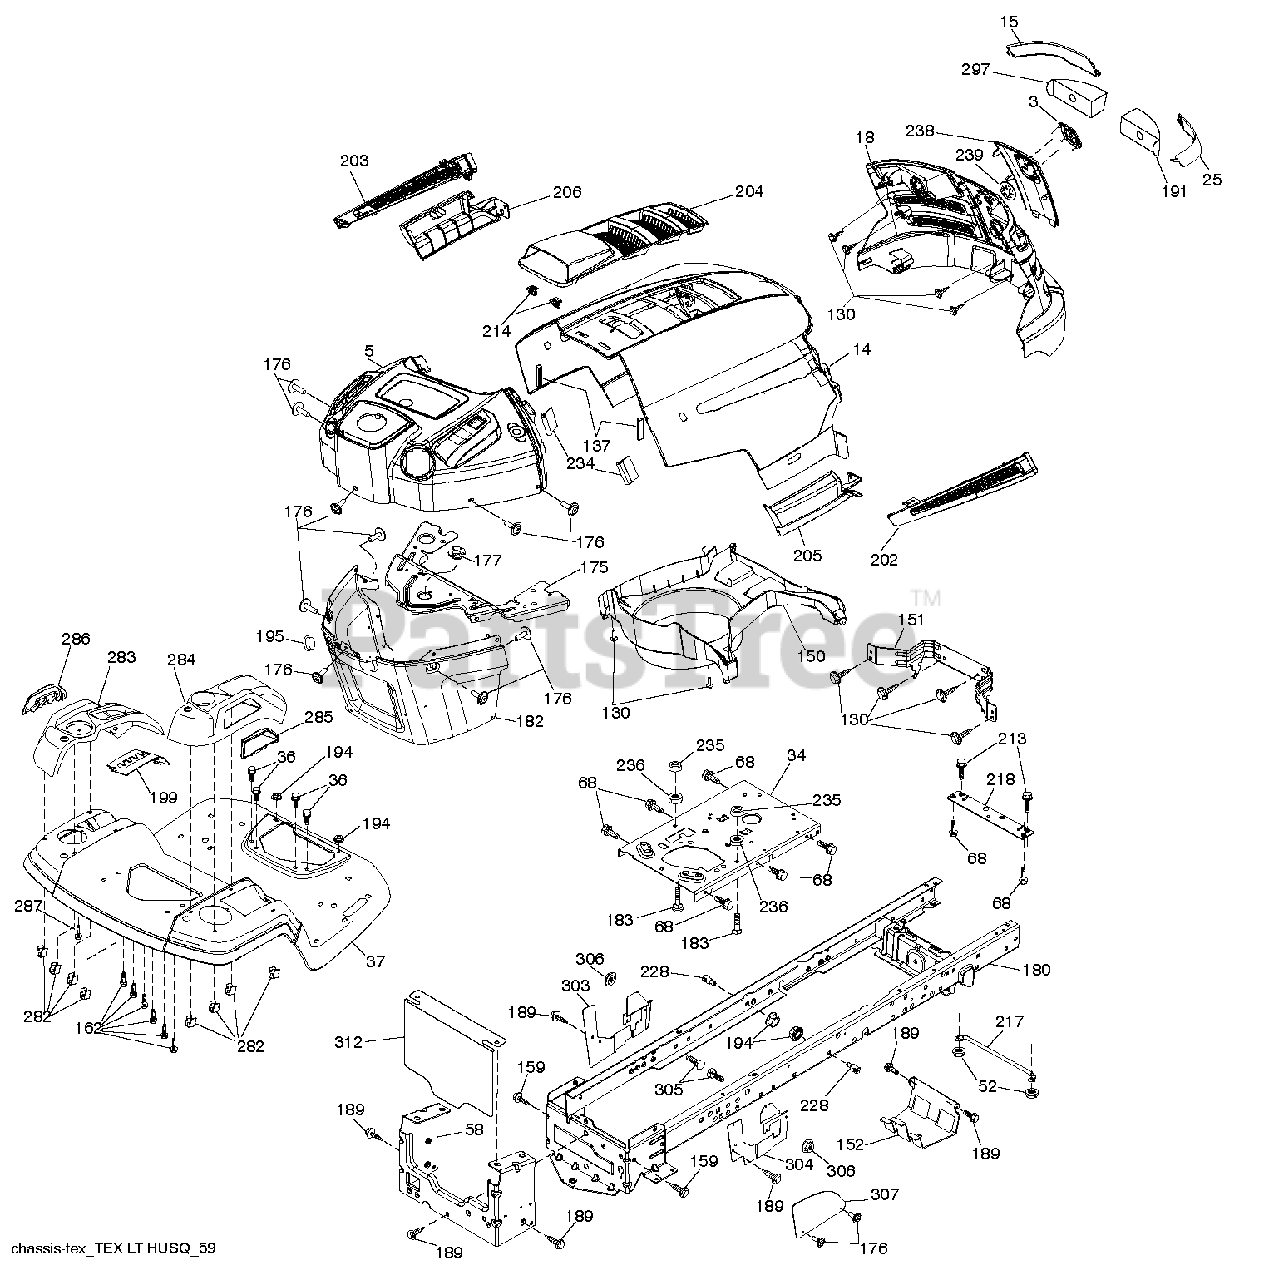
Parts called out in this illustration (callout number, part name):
3	LOGO.HUSQ.GT.LT.CROWN.H
5	SUBASM.DASH.UPPER.HLT.498
14	HOOD.HUSQVARNA.LT.ORANGE
15	LENS.HUSQVARNA LT.RH
18	GRILLE.SVC.HUSQVARNA.GREY
25	LENS.HUSQVARNA LT.RH
34	PLATE PLATE ENGINE
36	SCREW 5/16"
37	FENDER.TLT.FS.W/CUPHLD.ORANGE
52	LOCKNUT
58	DRAWBAR UPPER 2PC SMALL FENDER
68	SCREW LT
130	SCREW.#10 X 0.750.BOS
137	BUMPER DASH
151	BRACKET PIVOT
152	SHIELD.BROWNING.W/TEX
159	SCREW, 3/8-16X3/4
162	SCREW.HI-LO.CONSOLE
175	CROSSMEMBER
176	SCREW.#10-24X5/8.RN.QU
177	BUSHING STEERING
180	CHASS.WLDMNT.TL.12GA/2P.48/54
182	DASH.LOWER.PREDATOR LT
183	BOLT.5/16-18X1-1/4 FULL THD
189	SCREW
191	INSERT.REFLECTIVE.RH.
194	NUT LOCK HEX FLANGE 5/16-18
195	PLUG.TEX.DASH.SVC.MINDER.GREY
199	PLATE.DECK.LIFT.HUSQ.LT
202	VENT.SIDE.HUSQVARNA.LT.RT
203	VENT.SIDE.HUSQVARNA.LT.LFT
204	SUBASM.TOP.VENT.HUSQ.LT
205	SKIRT.SIDE.HUSQVARNA.LT.RT
206	SKIRT.SIDE.HUSQVARNA.LT.LEFT
213	BOLT
214	CLIP.RETAINER.TINNER.
217	ROD.PIVOT.HOOD
218	X-PIECE.HOOD.STOP.NON/
228	STUD.FASTNER.W/ANTI-ROTATE
234	BUMPER.HOOD.TEX.HUSQVARNA
235	SPACER FENDER
236	NUT.CENTERLOCK.5/16-
238	TRIM.HUSQ LT.668
282	CLIP.RETAINER.CONSOLE.LT.HUSQ
283	CONSOLE.ASM.LFT.RSF.HUSQ.LT
284	CONSOLE CONSOLE.HUSQ.SHIFT.HYD
285	CONSOLE INSERT RH
286	CONSOLE.INSRT.LH.HUSQ.LT.BLACK
287	SCREW 1/4X20
297	INSERT REFLECTIVE
303	SHIELD CHASSIS LEFT
304	SHIELD CHASSIS RIGHT
306	NUT LOCK FLG 3/8-16 UNC
307	SHIELD UPPER PEDAL
312	SHIELD.PNT.DRAWBAR.FRENCH
